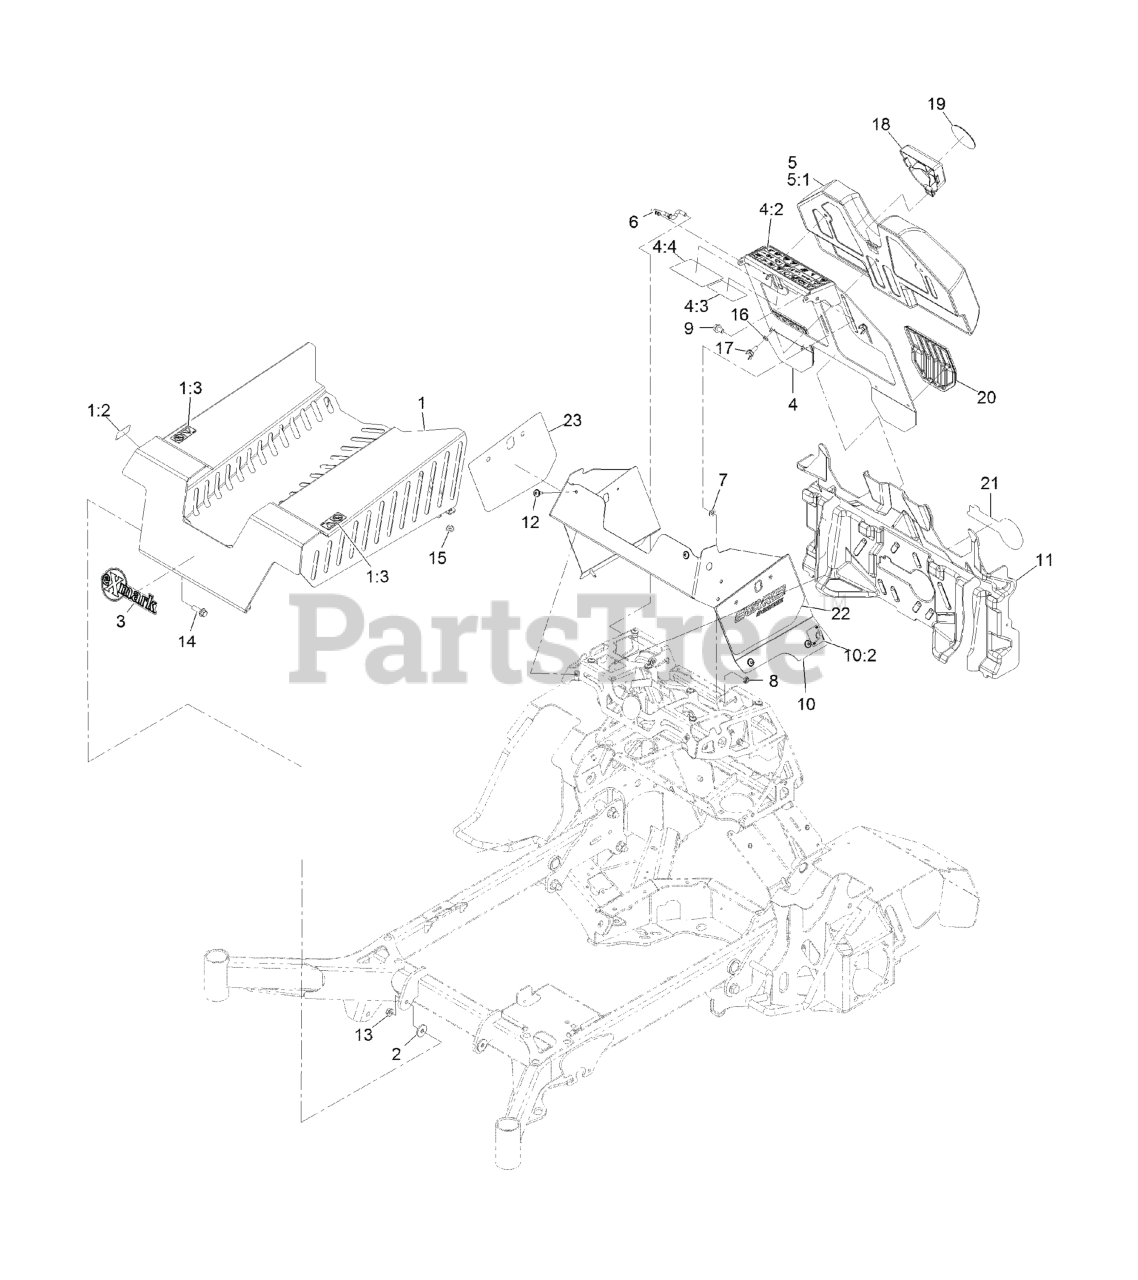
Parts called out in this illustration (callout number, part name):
1	ASM, FRONT COVER W/ DECALS
1:2	DECAL-WARNING
1:3	Decal-Warning
2	WASHER
3	DECAL, EXMARK LOGO
4	ASM, PAD BACKING W/ DECALS
4:2	DECAL-WARNING
4:3	DECAL-DRIVE RELEASE
4:4	DECAL-SERVICE AID
5	PAD, THIGH
5:1	COVER, PAD
6	ROD, PROP
7	WASHER-THRUST
9	SCREW-HHF
10	ASM, TOWER SKIN W/ DECALS
10:2	DECAL-PARK BRAKE, CE
11	PANEL, HEAT DEFLECTOR
12	SCREW, TORX
14	SCREW-HHF
16	WASHER-BELLEVILLE
17	SCREW, THUMB
18	INSERT, PAD
19	DECAL-X LOGO BADGE 3 IN
20	PAD, KNEE
21	DECAL-EXMARK LOGO
22	DECAL-STARIS LOGO LT
23	DECAL-STARIS LOGO RT
